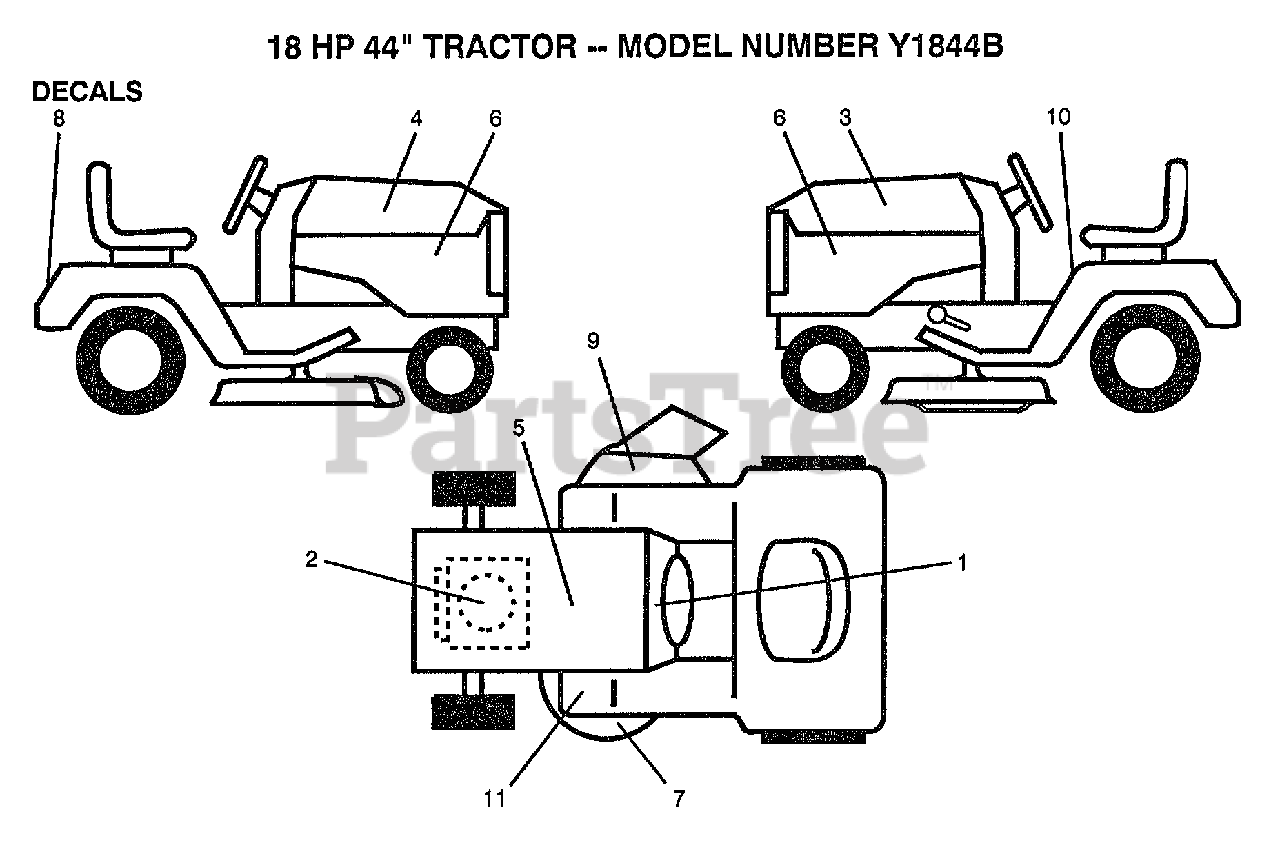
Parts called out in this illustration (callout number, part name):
2	"DECAL,HP ENGINE"
3	DECAL HOOD LH
5	DECAL
6	DECAL, SIDE PANEL
7	DECAL-INST YT
9	DECAL WARNING
10	DECAL CAUTION
11	DECAL T
